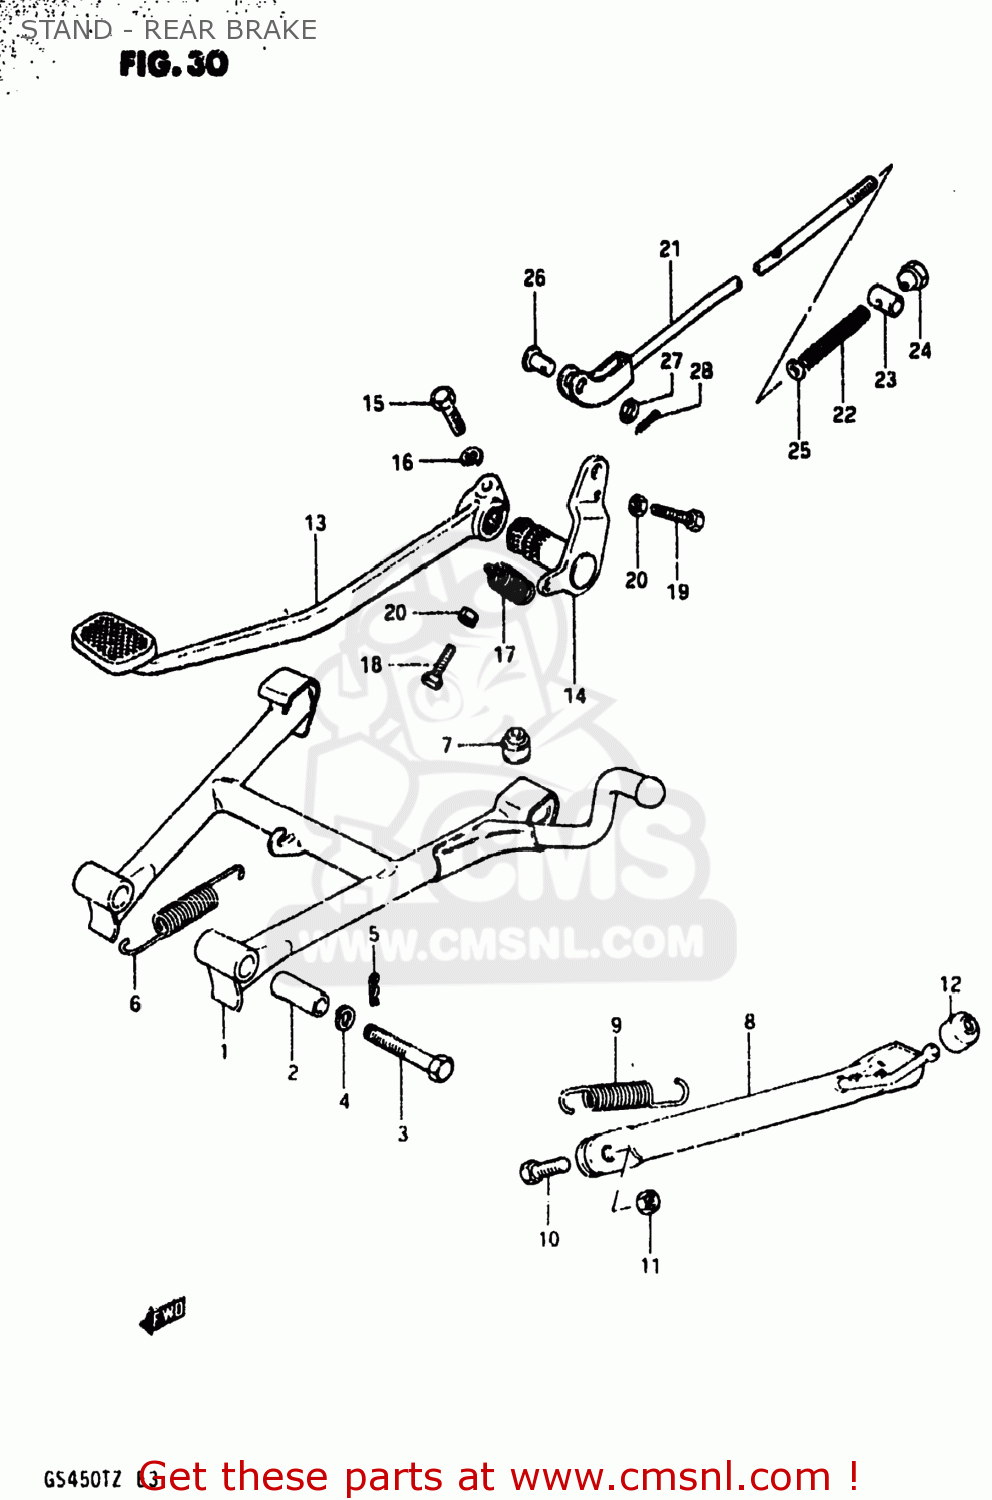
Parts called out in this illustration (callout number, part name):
1	STAND,CENTER
2	SPACER(10X16X38.8)
3	BOLT
4	LOCK WASHER
5	CLIP
6	SPRING
7	CUSHION
8	STAND,SIDE
9	SPRING
10	BOLT(10X30)
11	NUT
12	CUSHION
13	PEDAL,BRAKE
14	ARM,BRAKE PEDAL ROD
15	BOLT
16	LOCK WASHER
17	SPRING
18	BOLT
19	BOLT
20	NUT
21	ROD ASSEMBLY,REAR BRAKE
22	SPRING
23	PIN
24	NUT
25	WASHER
26	PIN(L:13.5)
27	WASHER
28	PIN 20X20
